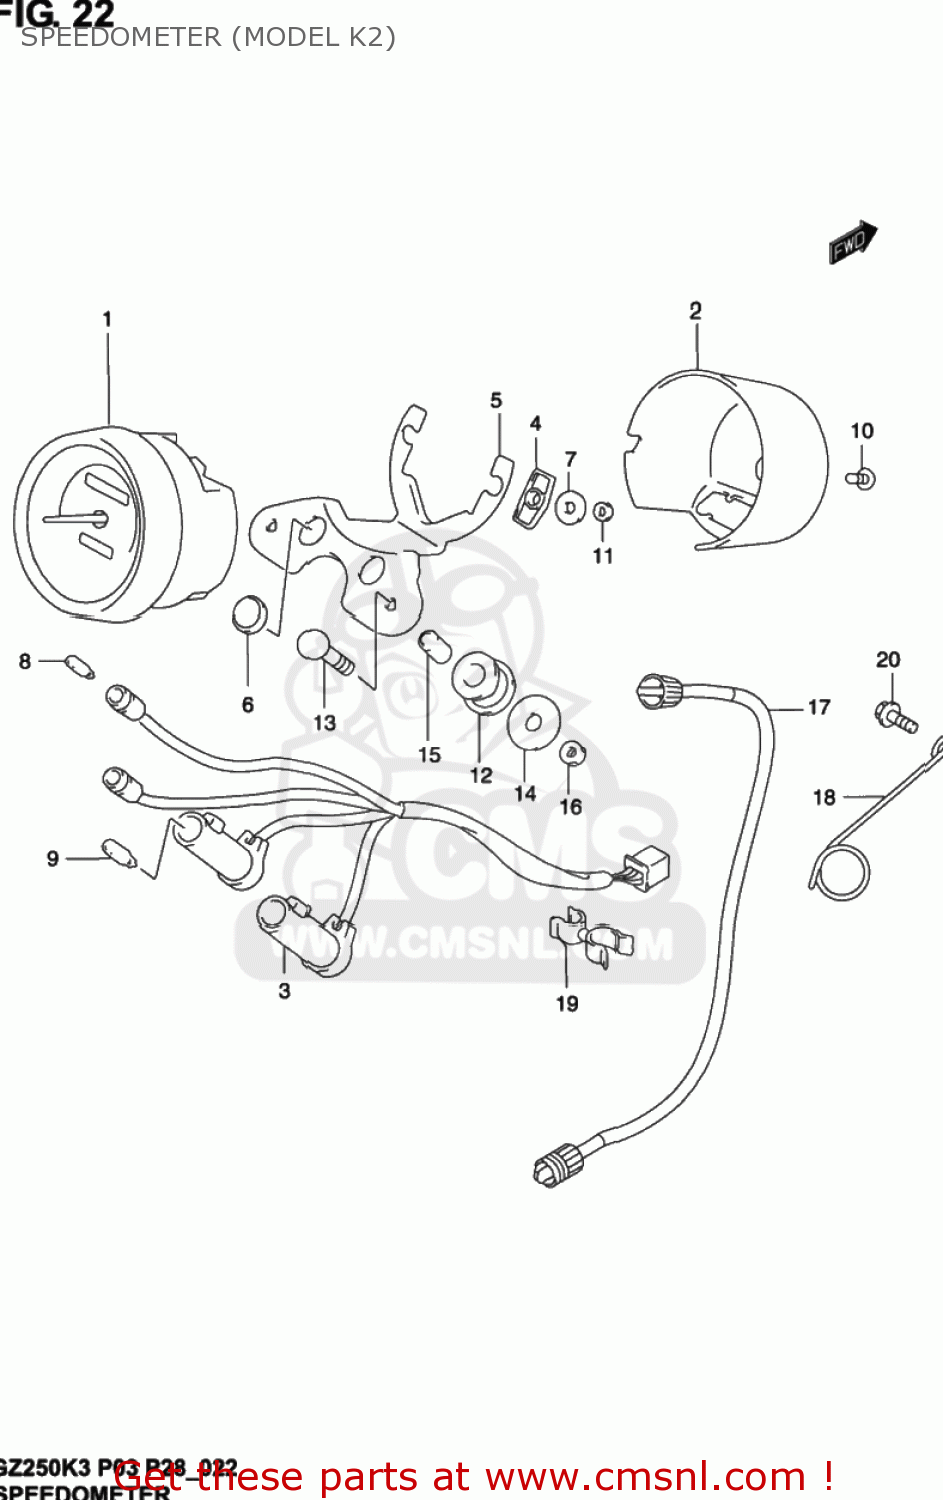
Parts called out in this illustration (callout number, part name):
1	SPEEDOMETER
2	COVER,UNDER(CHROMUN)
3	SOCKET ASSY
4	CUSHION,DAMPER
5	BRACKET,METER
6	LENS(GREEN)
7	WASHER(5.2X16X1)
8	BULB(12V3.4W,T10)
9	BULB(12V1.7W,T6.5)
10	SCREW
11	NUT
12	CUSHION,METER BRACKET
13	BOLT(6X30)
14	WASHER(6.5X28X1.6)
15	SPACER(6.5X10X15.7)
16	NUT 6MM
17	CABLE ASSY,SPEEDOMETER
18	GUIDE,SPEEDOMETER CABLE
19	CLAMP
20	BOLT
